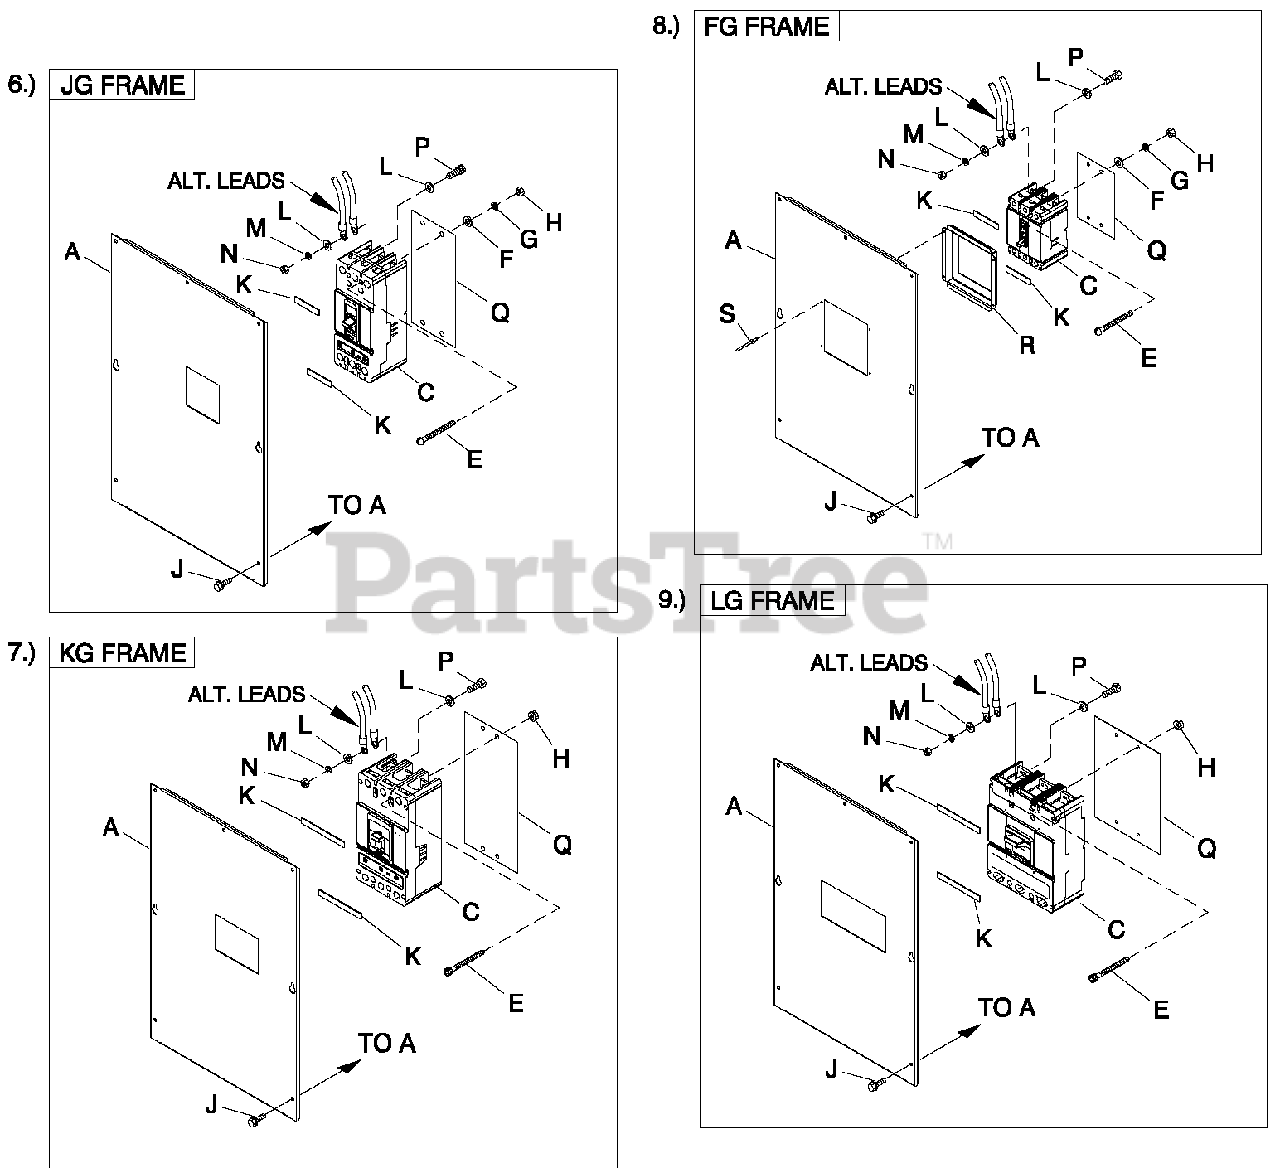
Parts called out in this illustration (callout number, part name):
6	UL CIRCUIT BREAKER (JC)
7	UL CIRCUIT BREAKER (KG
8	UL CIRCUIT BREAKER (3P FG)
9	UL CIRCUIT BREAKER (LG)
A	COVER CB E JG FRAME C5
C	CB 0250 3P 600V E JG LL
E	SCREW RHM 1/4-20X3
F	WASHER FLAT 1/4-M6 ZINC
G	WASHER LOCK M6-1/4
H	NUT HEX 1/4-20 STEEL
J	SCREW THF M6-1 X 16 N WA Z/JS
K	TAPE ELEC 1/2 FOAM
L	WASHER FLAT 5/16-M8 ZINC
M	WASHER LOCK M8-5/16
N	NUT HEX M8-1.25 G8 CLEARZINC
P	SCREW HHC M8-1.25 X 25 C8.8
Q	INSULATOR CB E 3P JG
A	COVER CB E KG FRAME C5
C	CB 0350 3P 600V E KG LL
E	SCREW SHC M6-1.0 X 50 C8.8
H	NUT FLANGE M6-1.0 NYLOK
Q	INSULATOR CB E 3P KG
A	COVER CB G 225AF C5
C	CB 0150 3P 480V E FG LL
E	SCREW PPHM #8-32 X 1-3/4 ZINC
F	WASHER FLAT #8 ZINC
G	WASHER LOCK #8-M4
H	NUT HEX #8-32 STEEL
L	WASHER FLAT #10 ZINC
M	WASHER LOCK M5
N	NUT HEX M5-0.8 G8 CLEAR ZINC
P	SCREW HHC M5-0.8X 20 G8.8
Q	INSULATOR CB 3P E TYPE CC/FG
R	COVER CB DISH 3P E FD
S	RIVET POP .125 X .275 SS
A	COVER CB E LG FRAME C5
C	CB 0450A 3P 600V E LG LL
Q	INSULATOR CB E 3P LG
